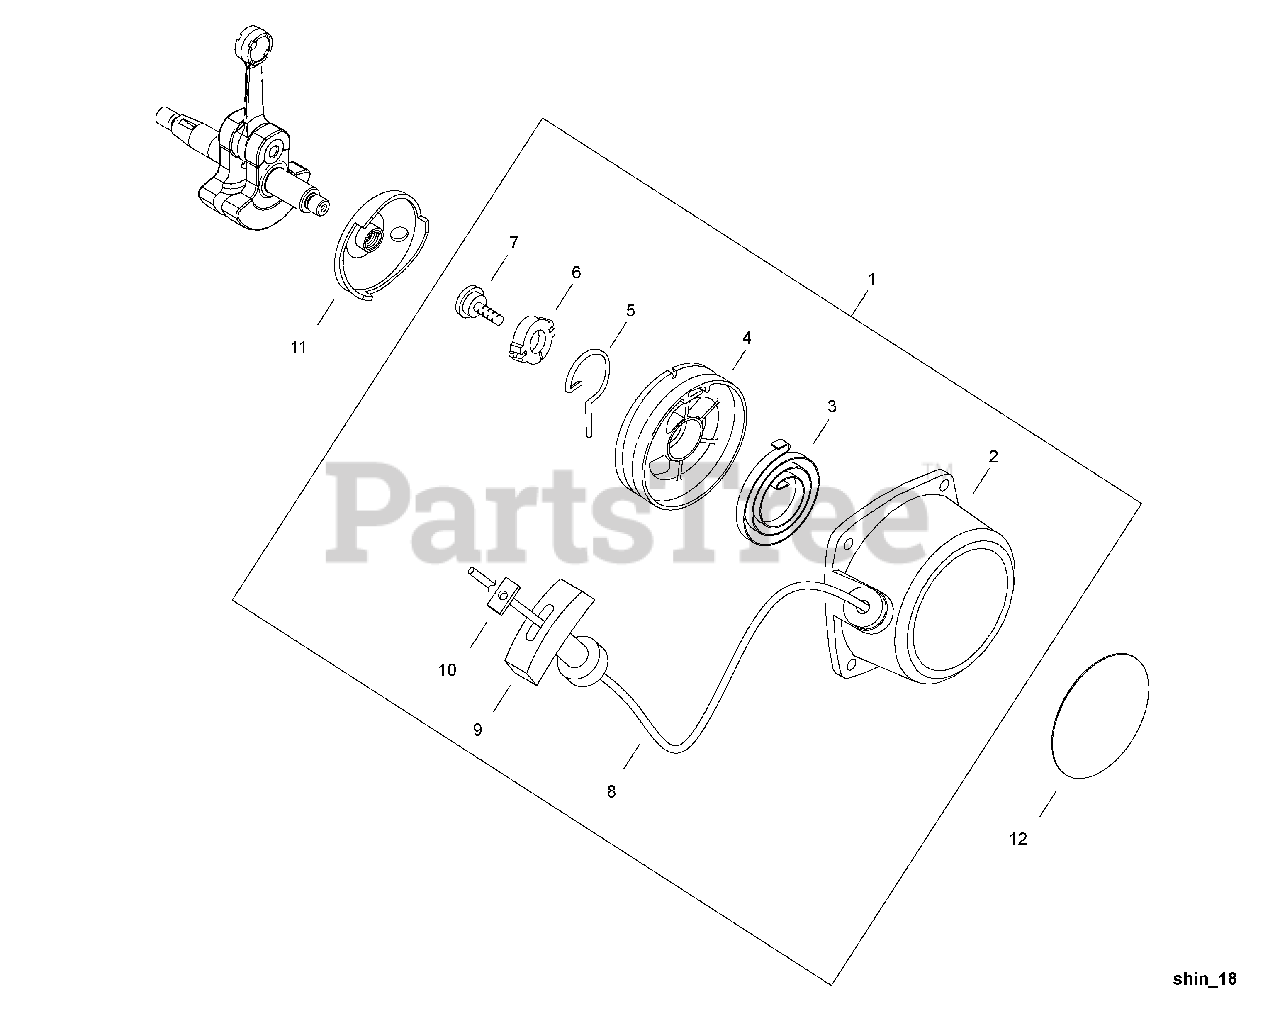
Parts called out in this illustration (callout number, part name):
1	STARTER ASSY
2	CASE, STARTER
3	SPRING, REWIND
4	REEL, ROPE
5	PAWL, STARTER
6	WASHER - 5
7	SCREW - 5
8	ROPE, STARTER
9	GRIP, STARTER
10	RETAINER, ROPE
11	STARTER PAWL ASSY
12	LABEL - MODEL T282
